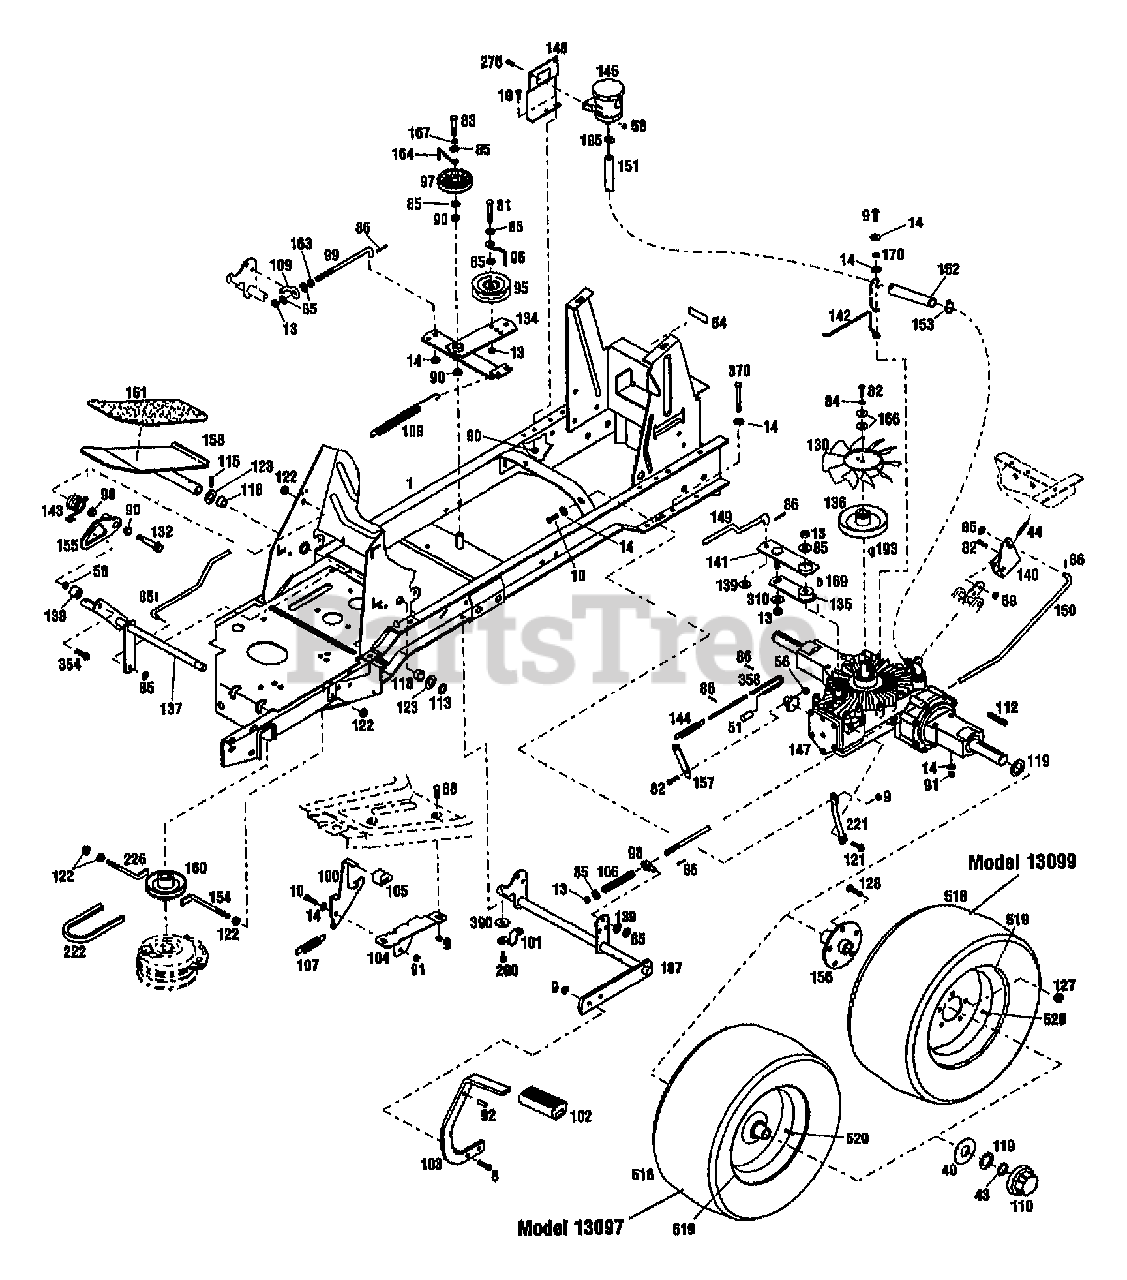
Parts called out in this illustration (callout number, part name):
1	ASSM-FRAME LTX {13097}
1	ASSM-FRAME {13099}
8	SCR-HH 5/16-18X1.0 G5 ZP
9	NUT-HFLK 5/16-18 ZP
10	SCR-HHC 5/16-18X.75 GR 5 ZP
13	NUT-LOCK 3/8-16
14	WASHER-FLAT 5/16 SAE
40	WASHER-SPEC .75X2.50
43	RING-HEAVY EXT HD 1.0 ID
44	SPRING-EXTENSION
51	GRIP-HANDLE
54	DECAL-TRANS RELEASE
56	NUT-HF/LK 1/4-20 ZP
58	NUT-HT LK 1/4-20
81	SCR-HH 3/8-16X2.0 G5 ZP
82	SCR-HH 1/4-20X1.0
83	SCR-HH 3/8-16X1.75 G5 ZP
84	WASHER-LK .25 ZP
85	WASHER-FLAT 3/8 SAE
86	PIN-COTTER .09X.75 ZP
88	SCR-CARR 5/16-18X.62 G2 ZP
90	BUSHING-.5X.5 NYLON FLNG
91	NUT-TOP/LK 5/16-18 ZP
92	PIN-DRIVE .312X.75
96	GUIDE-BELT
97	PULLEY-IDLER
98	SWIVEL
99	ROD-CLUTCH
100	LATCH-BRAKE LOCK
101	CLIP-CLAMP .75 ID
102	PAD-FOOT PEDAL
103	PEDAL-BRAKE
104	BRKT-BRAKE LOCK
105	PAD-BRAKE
106	SPRING-COMPRESSION
107	SPRING-EXTENSION
108	SPRING-EXTENSION
109	ROD-PIVOT
110	CAP-HUB
112	KEY-.25 SQ X 2.0
113	RING-RETAIN .625 ID
115	PIN-ROLL .188X1.0
118	BEARING-FLANGE
119	WASHER-SPEC
121	SCR-HFLK 5/16-18X.50 ZP
122	NUT-HFLK 3/8-16 ZP
123	WASHER-1.115X.637X.06
127	NUT-LUG 7/16-20 {13099}
128	BOLT-WHEEL {13099}
130	FAN-HYDRO TRANSMISSION
132	SCR-SHLDR 3/8-16
134	ARM-IDLER
135	ARM-HYDRO
136	PULLEY-HYDRO
137	SHAFT-HYDRO PIVOT
138	BEARING-BALL
139	WASHER-FLAT .375DIA
140	BRKT-BRAKE HYDRO
141	ARM-CONTROL HYDRO
142	GUIDE-BELT
143	SPRING-TORSION
144	SPRING
145	TANK-EXPANSION
147	TRANSMISSION
148	SUPT-EXPANSION TANK
149	ROD-CONTROL HYDRO
150	ROD-BRAKE
152	SUPPORT-HOSE
153	CLAMP-HOSE 5/8
154	RETAINER-CLUTCH
155	ARM-RETURN NEUTRAL HYDRO
156	HUB-WHEEL {13099}
157	VALVE-DUMP
158	ASSM-PEDAL HYDRO
160	PULLEY-ENGINE
161	PAD-FOOT PEDAL
163	NUT-HEX 3/8-16 ZP
164	GUIDE-BELT
166	WASHER-FLAT 1.25X.28X.062 ZP
167	WASHER-LK .375 @ DEPL
169	KEY-WOODRUFF .125X.5
170	WASHER-LK .312 ZP
185	CLAMP-HOSE
187	ASSM-PEDAL
193	KEY-WOODRUFF
200	SCR-HFLK 5/16-18X.75
221	SUPPORT-TRANSMISSION
226	GUIDE-BELT
275	SCR-HH 1/4-20X.625 G5 ZP
310	WASHER-LK .375 PYRAMIDAL
354	SCR-HFLK 1/4-20X1.25 G5ZP
358	ROD-DUMP VALVE
370	SCR-HH 5/16-18X3.0
390	WASHER-.632X.39X.0329
518	TIRE-20X8.00-10 {13097}
518	TIRE {13099}
519	RIM {13097}
519	RIM-WHEEL REAR {13099}
520	STEM-VALVE
